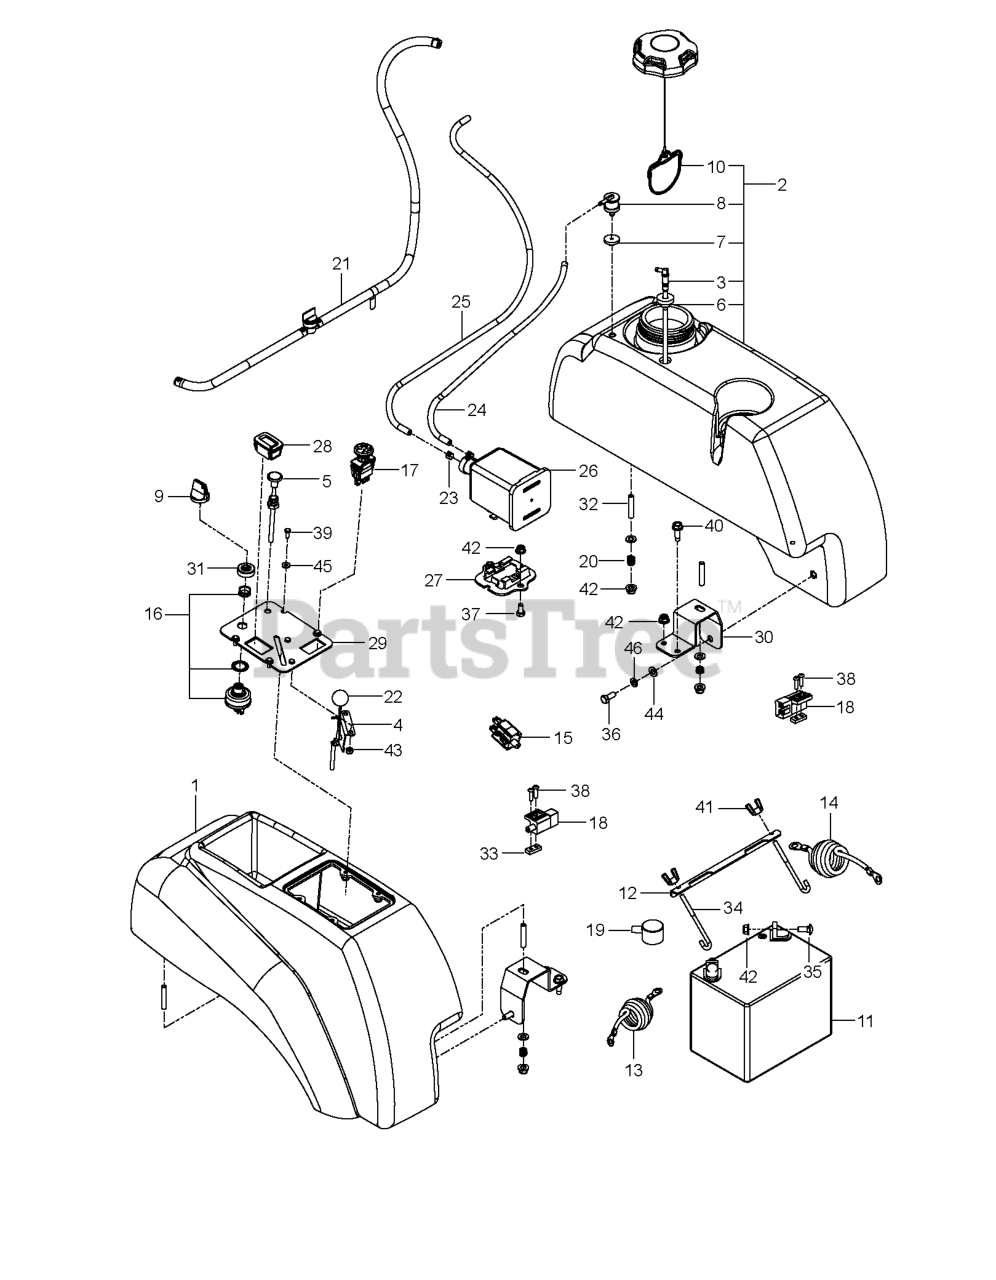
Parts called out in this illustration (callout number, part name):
1	FENDER CONSOLE
2	FUEL.TANK.ASSY.LH.MZ.GRY
3	FITTING, FUEL
4	THROTTLE CONTROL W/BALL KNOB
5	CABLE, CHOKE
6	RUBBER GROMMET
7	GROMMET, CHECK VALVE
8	VALVE.FUEL.CHECK
9	KEY, IGNITION
10	CAP, FUEL
11	BATTERY, 12 V 330 AMP
12	BRACKET.BATTERY.MOUNT.PLATED
13	CABLE.BATT.SOLENOID.MZ.RED.25"
14	CABLE.GROUND.BATT.MZ.BLACK.39"
15	SWITCH.INTRLCK.CLUTCH.
16	SWITCH, IGNITION, INDAK
17	RP SWITCH.PTO.TERMINAL.STD.RED
18	SWITCH INTERLOCKT
19	COVER.TERMINAL.BATTERY
21	FUEL.HOSE.SHUT.OFF.ASM.10".26"
22	KNOB.ROUND.BALL.BLACK
23	CLAMP, HOSE
24	HOSE.3/16".VAPOR.LINE.36"LGTH
25	HOSE.3/16".VAPOR.LINE.27"LGTH
26	CANNISTER, CARBON
27	BRACKET, CANISTER
28	GUAGE.SRVCMNDR.HRMTR.
29	PLATE, CONSOLE, BLK
30	SUPPORT, TANK, BLK
31	CAP IGNITION NUT
32	STUD, 5/16C
33	PLATE NUT ZTR
34	HOOK, "J"
34	WASH.5/16.SLW.ZD
35	RP BOLT 5/16-18 X3/4 ZN/YEL GR
36	BOLT.FIN.HEX.5/16-18X3/4
37	HCS 5/16-18 X 5/8 GR 5 ZD
38	SCR #10-24 X .75 SKT HD BLK
39	HCS #10-24 X 1/2
40	SCREW
41	WING NUT 1/4
42	5/16-18 NYLOC FLANGE NUT
43	NUT 10-24 NYLOC
44	WASHER
46	WASH.5/16.SLW.ZD
